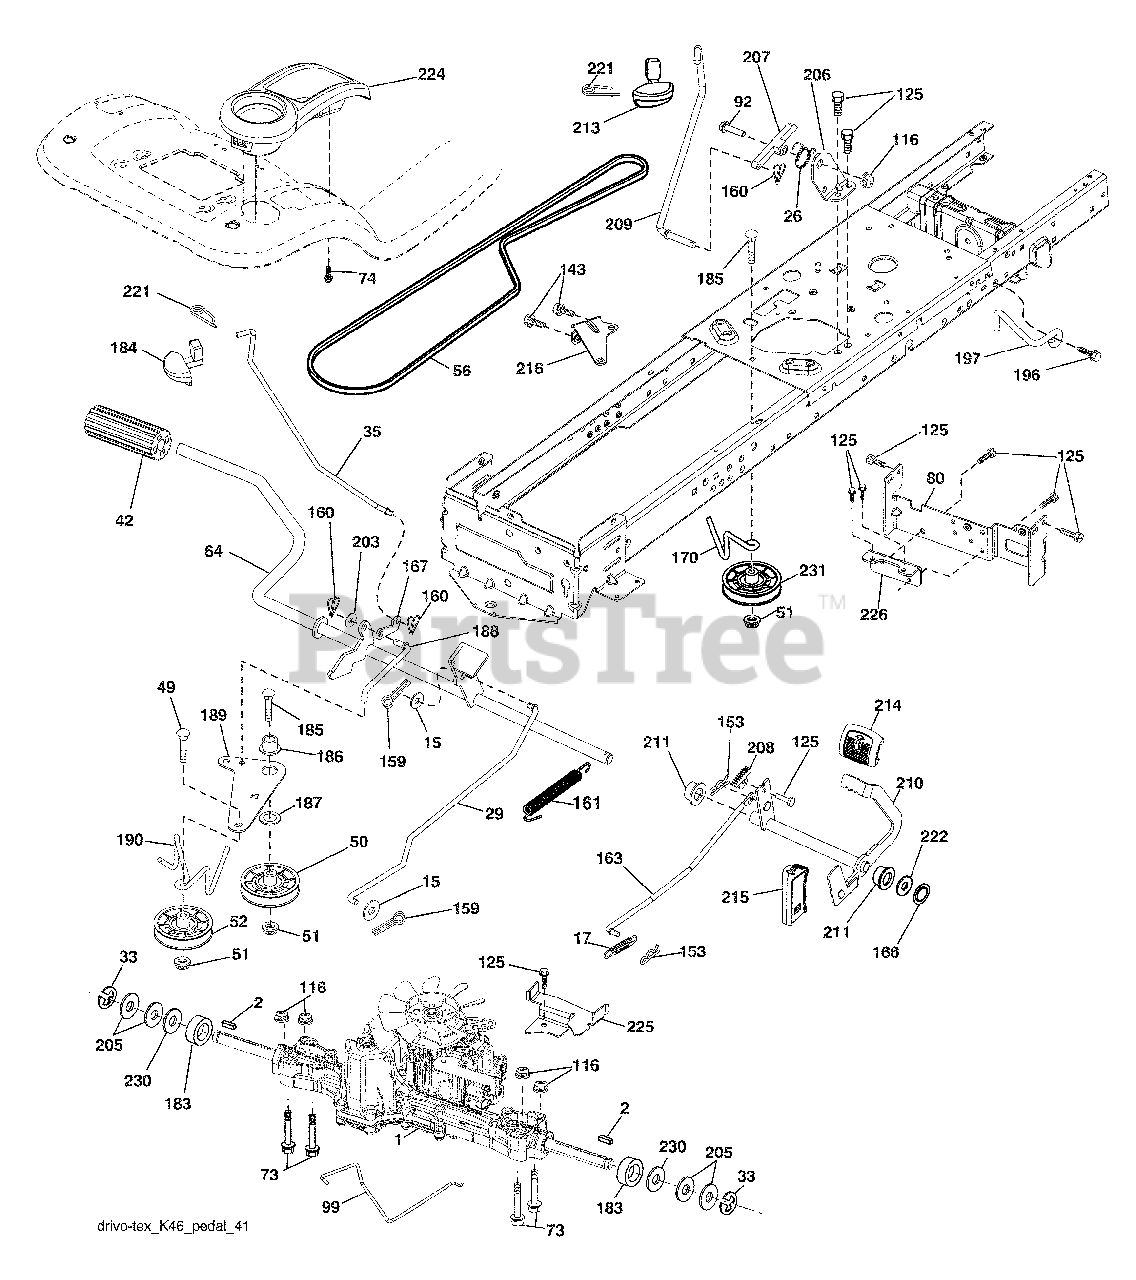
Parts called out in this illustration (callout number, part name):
1	Transaxle, TUFFTORQ K46 BT
2	Key 1/4 x 2.5
15	Washer 13/32 x 13/16 x 16 Ga.
17	Spring, Brake
26	Spring Return Cruise
29	Rod, Brake
35	Rod, Brake, Park
42	Cover, Foot Pedal
50	Pulley Idler Flat
51	Lock Nut 3/8-16
52	Idler V-Groove 910" Offset
56	V-Belt, Drive
64	Shaft Asm. Pedal Brake Control
73	Bolt Hex Flghd. 5/16-18 x Gr. 5
74	Screw 1/4 x 1/2
80	Bracket Strap Torque
92	Bolt Fin. Hex 5/16-18 unc x 1.25
99	Rod Bypass
116	Nut Lock Hex Flange 5/16-18
125	Screw 5/16-18 x 3/4
143	Screw 5/16-18 x 1/2
153	Retainer Spring
159	Pin Cotter 1/8 x 3/4
160	Retainer Clip
161	Spring, Return, Clutch
163	Rod Pedal Control
166	Nut Push .625
167	Latch Brake Parking
170	Keeper Belt Centerspan
183	Spacer Split
184	Handle Parking Brake
185	Bolt Rdhd. Sqnk. 3/8-16 unc x 2 - 3/4
186	Spacer Retainer
187	Washer
188	Link Clutch Ground Drive
189	Bellcrank Ground Drive
190	Keeper Bellcrank Ground Drive
196	Screw 3/8-16 x 1
197	Link Clutch Anti-Rotation
206	Bracket Mount Latch Cruise
207	Latch Control Cruise
208	Gear Sector Control Cruise
209	Rod Control Cruise
210	Rocker Asm. Pedal Control
211	Bearing Nylon
213	Knob Control Cruise
214	Pedal Forward
215	Pedal Reverse
216	Bracket Pulley Idler
221	Retainer Spring Clip Handle
222	Washer 21/32 x 1-1/4 x 10 Ga.
224	Console Toolbox
225	Keeper Belt Trans.
226	Bracket Mount Torque
230	Washer Hardened
231	Idler V-Groove
